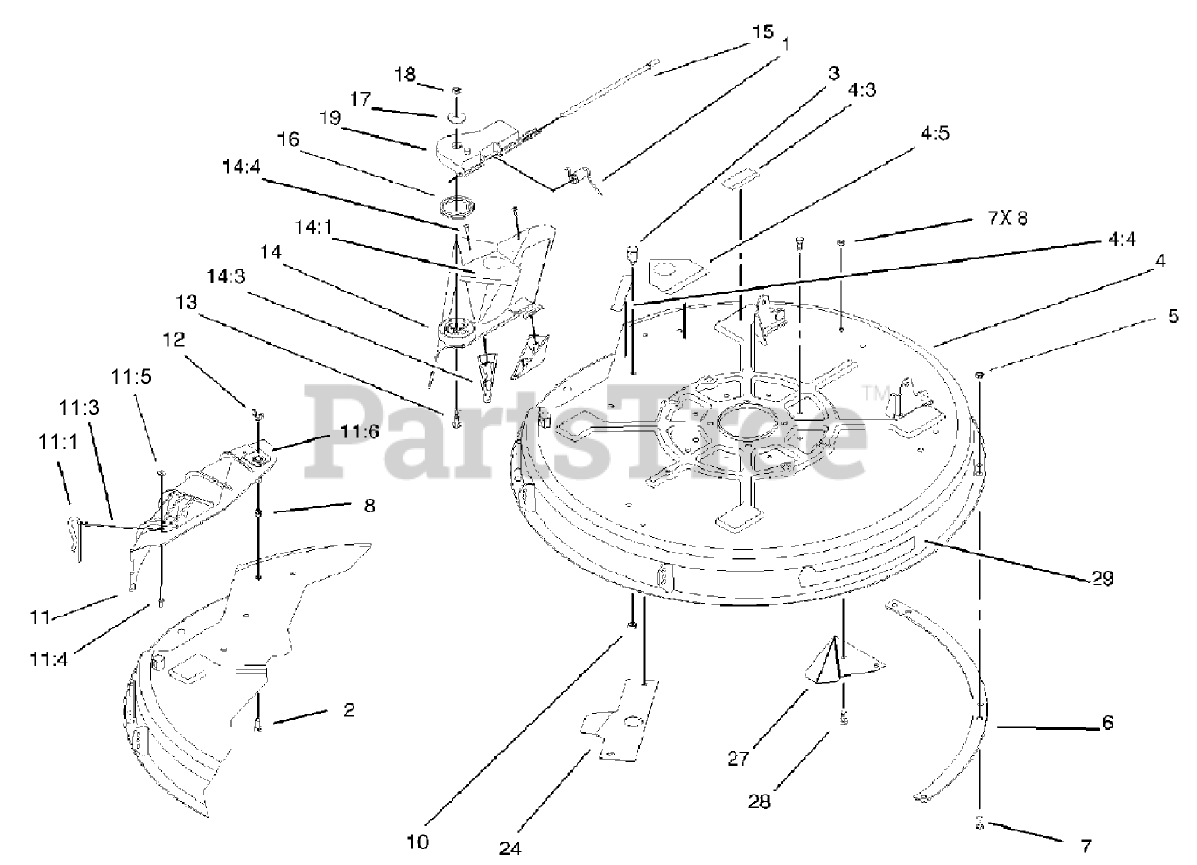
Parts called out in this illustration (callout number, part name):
1	SPRING-TORSION
2	SCREW-HH
3	POST-PIVOT
4	DECK ASM
4:3	DECAL-WARNING
4:4	DECAL-DANGER
4:5	DECAL-DANGER
5	NUT-LOCK, NI
6	RING-DECK
7	SCREW-HH
8	NUT-LOCK, NI
11:1	PIN-LOCKING, CHUTE
11:3	LANYARD
11:4	RIVET-BLIND
11:5	WASHER-PLAIN
12	NUT-WING
13	BOLT-SHOULDER
14	32 INCH DEFLECTOR ASM
14:1	DECAL-DANGER
14:3	KICKER
14:4	SCREW-PPH
15	ROD-HINGE, DEFLECTOR
16	SPRING-TORSION
18	NUT-LOCK, NI
19	PIVOT-HINGE, DEFLECTOR
24	RAMP-DEFLECTOR
28	SCREW-HH
29	DECAL-RECYCLER
